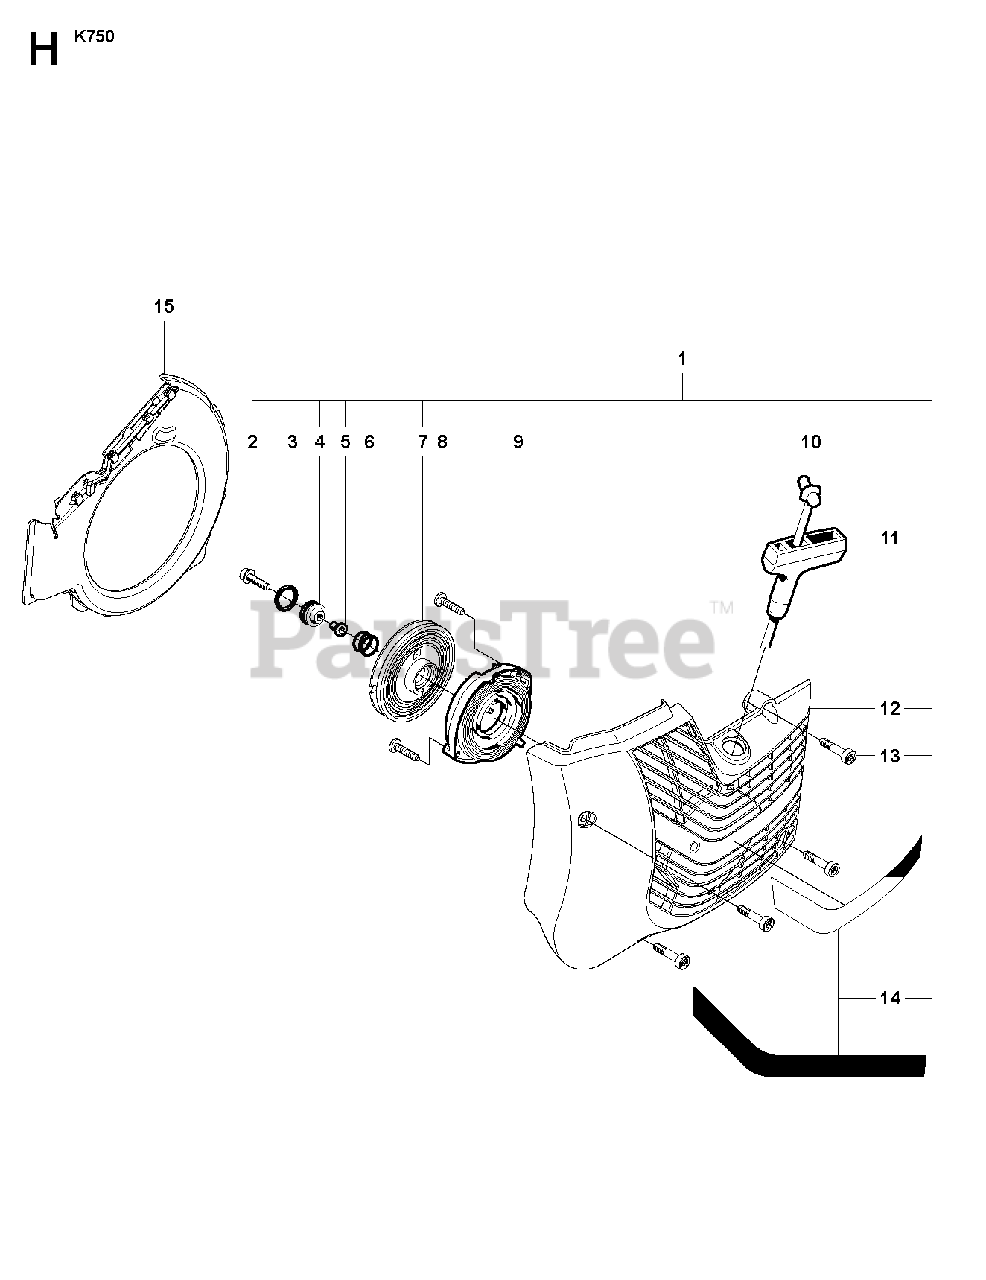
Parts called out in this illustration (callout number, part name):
1	STARTERIncl. 2 - 14
2	SCREW IHSCFT
4	GROMMET
5	SPACING SLEEVE
6	COMPRESSION SPRING
7	STARTER PULLEY
8	SCREW CCRPANT
9	RECOIL SPRING
11	STARTER HANDLE
12	STARTER COVER
13	SCREW ITXSCM
14	LABEL
15	AIR CONDUCTOR
